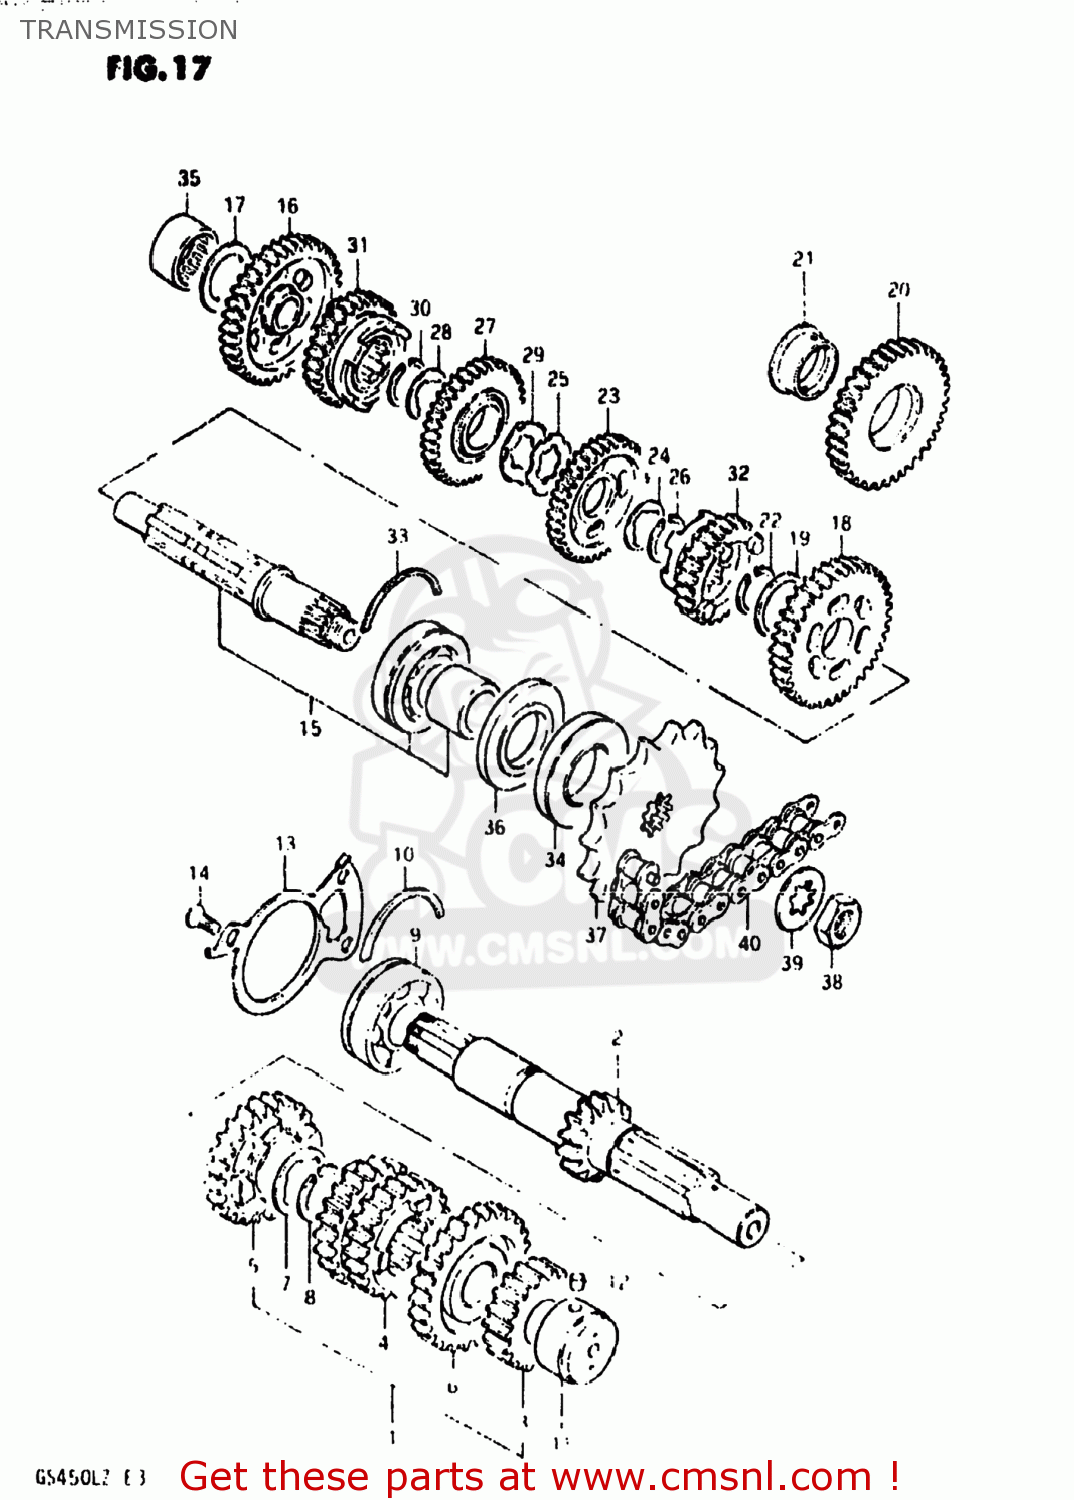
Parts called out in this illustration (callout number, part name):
1	SHAFT,COUNTER
2	SHAFT,COUNTER
3	GEAR,2ND DRIVE(NT:18)
4	GEAR,THIRD DRIVE
5	GEAR,FIFTH DRIVE
6	GEAR,SIXTH DRIVE
7	WASHER
8	CIRCLIP
9	BEARING(25X62X17)
10	C-RING
11	ROLLER BEARING (20X34X1
12	PIN
13	PLATE,COUNTERSHAFT BEARING
14	SCREW
15	SHAFT,DRIVE
16	GEAR,FIRST DRIVEN
17	WASHER
18	GEAR,SECOND DRIVEN
19	WASHER
20	GEAR,SECOND DRIVEN
21	BUSHING
22	CIRCLIP
23	GEAR,THIRD DRIVEN
24	WASHER,LOCK
25	WASHER,LOCK
26	CIRCLIP
27	GEAR,FOURTH DRIVEN
28	WASHER,LOCK
29	WASHER
30	CIRCLIP
31	GEAR,5TH DRIVEN(NT:25)
32	GEAR,SIXTH DRIVEN
33	C-RING
34	SEAL,OIL(32X64X8)
35	ROLLER BEARING (20X34X1
36	SEAL,OIL(32X62X5.5)
37	SPROCKET,ENGINE(NT:16)
38	NUT
39	WASHER
40	CHAIN ASSEMBLY,DRIVE
